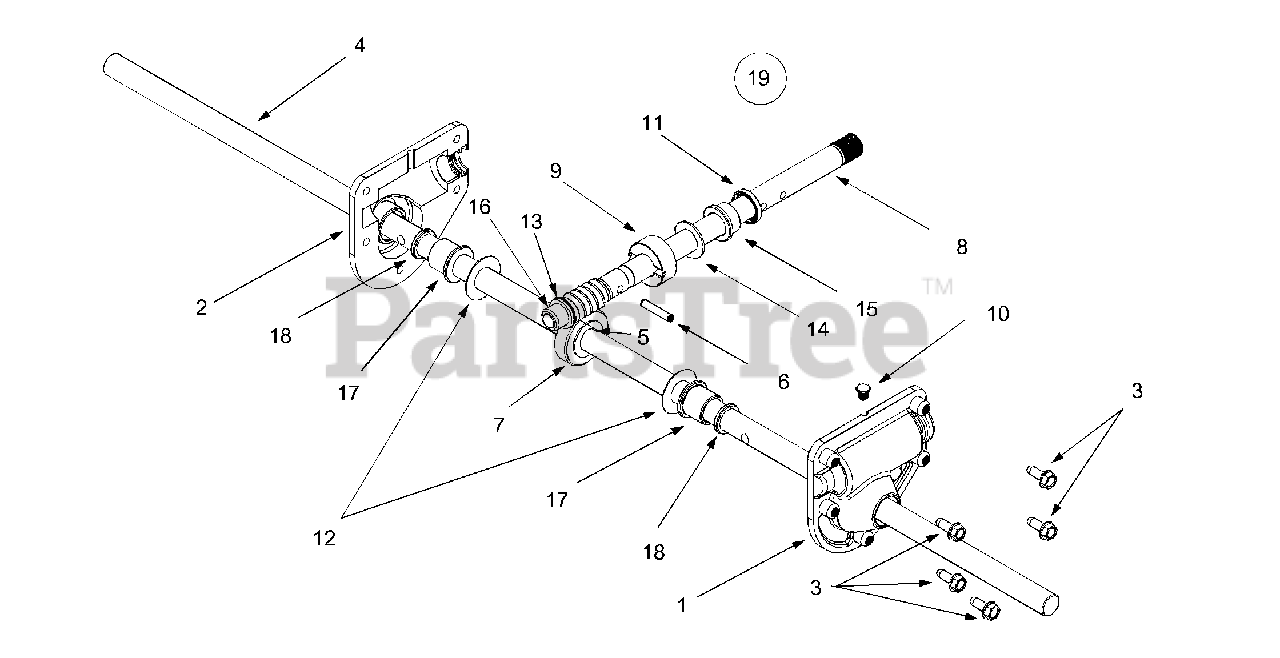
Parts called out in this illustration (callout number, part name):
1	RH Reducer Housing
2	LH Reducer Housing
3	Self Tapping Screw, 1/4-20 x .75
4	Spiral Axle, 30
5	Hi-Pro Key, 3/16 x 5/8
6	Spring Spirol Pin, .25 x 1.25
7	Worm Gear, 20-tooth
8	Worm Shaft
9	Thrust Collar
10	Grease Plug
11	Grease Seal
12	Flat Washer, .76 x 1.5 x .030
13	Flat Washer, .508 x 1.0 x .020
14	Flat Washer, .76 x 1.5 x .060
15	Flange Bearing, .75 x 1.0 x .59
16	Flange Bearing, .75 x 1.0 x .925
17	Flange Bearing, .754 x 1.0 x .925
18	Grease Seal
19	Gear Assembly Complete, 30"
